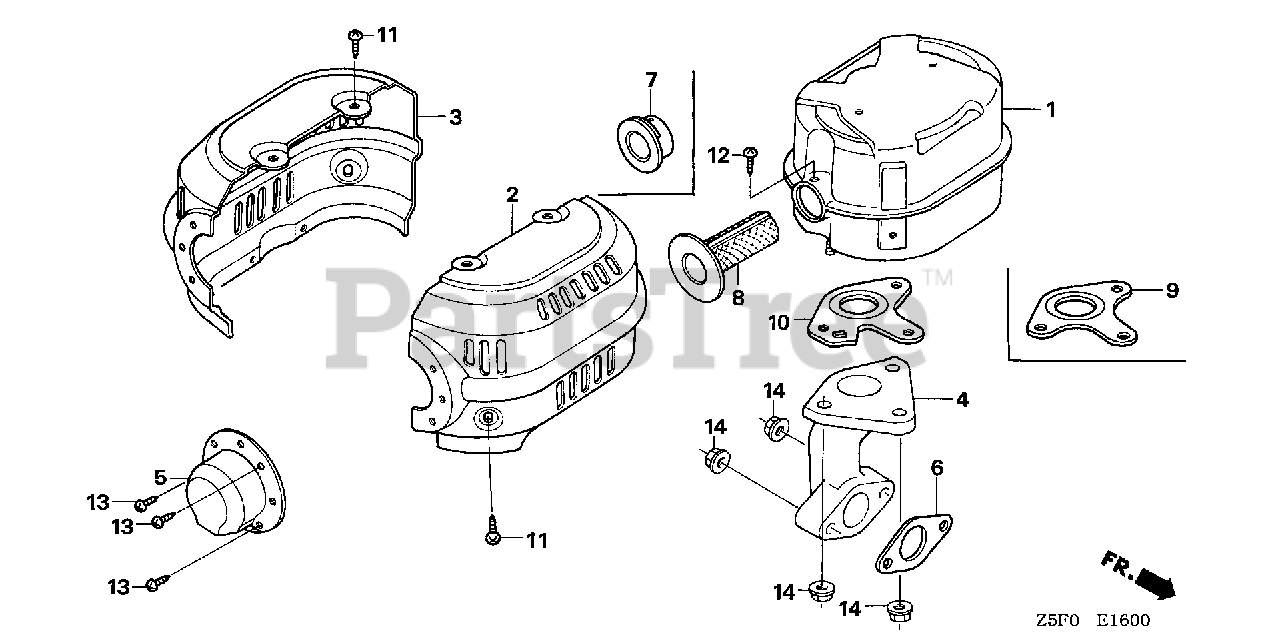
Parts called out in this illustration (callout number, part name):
1	MUFFLER (SILENT)
2	PROTECTOR, R. MUFFLER (SILENT)
3	PROTECTOR, L. MUFFLER (SILENT)
4	PIPE, EX.
6	GASKET, EX. PIPE
7	FLANGE, BAFFLE
8	ARRESTER, SPARK
9	GASKET, MUFFLER (NIPPON LEAKLESS)
10	GASKET, MUFFLER (ARRESTER)
11	SCREW, TAPPING (5X8)
12	SCREW, TAPPING (4X6) (TO INSTALL OPTIONAL SPARK ARRESTER)
14	NUT, FLANGE (8MM)
